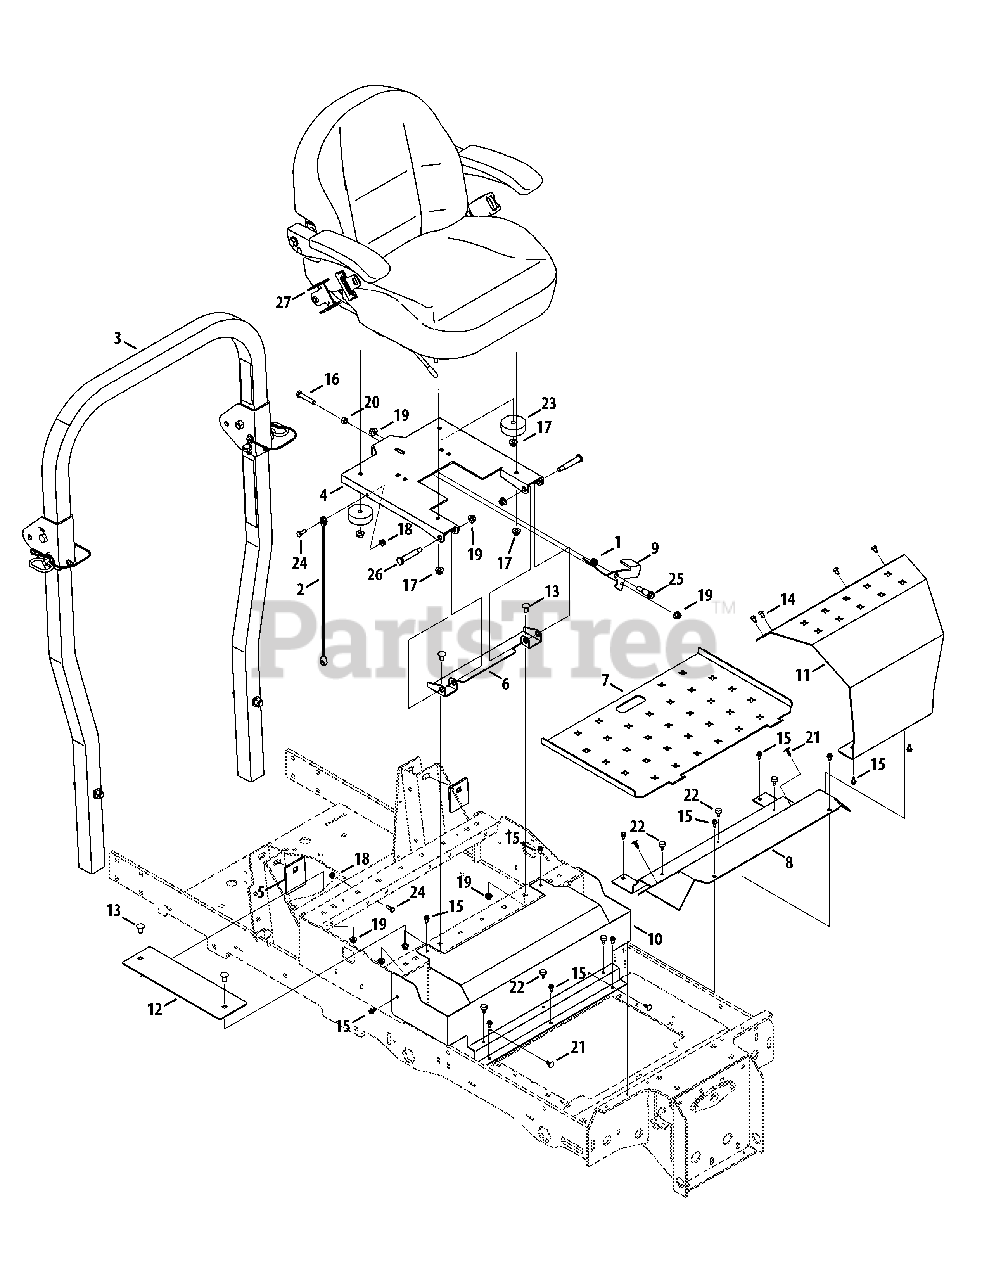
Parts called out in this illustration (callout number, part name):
1	Torsion Spring, .725 x 1.0 x .09
2	Cable Support
3	Folding ROPS Assembly
4	Seat Mounting Bracket
5	Deck Reinforcement Plate
6	Seat Mounting Bracket
7	Floor Panel Tray
8	Floor Panel
9	Seat Lever Latch
10	Control Panel Cover
11	Front Panel Cover
12	Seat Panel Cover, RH
13	Carriage Bolt, 3/8-16 x .75
14	Screw, 1/4-20 x .5
15	Hex Flange Screw, 1/4-20 x .500
16	Hex Cap Screw, 3/8-16 x 2.50
17	Nut, 5/16-18, Flangelock
18	Nut, 1/4-20, Flangelock
19	Nut, 3/8-16, Flangelock
20	Nut, 3/8-16, Hex
21	Clip, .250 Dia.
22	Bumper, .62 Dia. x .3
23	Rubber Bumper, 2.5 x 1.0
24	Shoulder Screw, .31 x .50, 1/4-20
25	Shoulder Bolt, .50 x .925, 3/8-16
26	Shoulder Bolt, .500 x 2.23, 3/8-16
27	Seat, w/ Suspension
